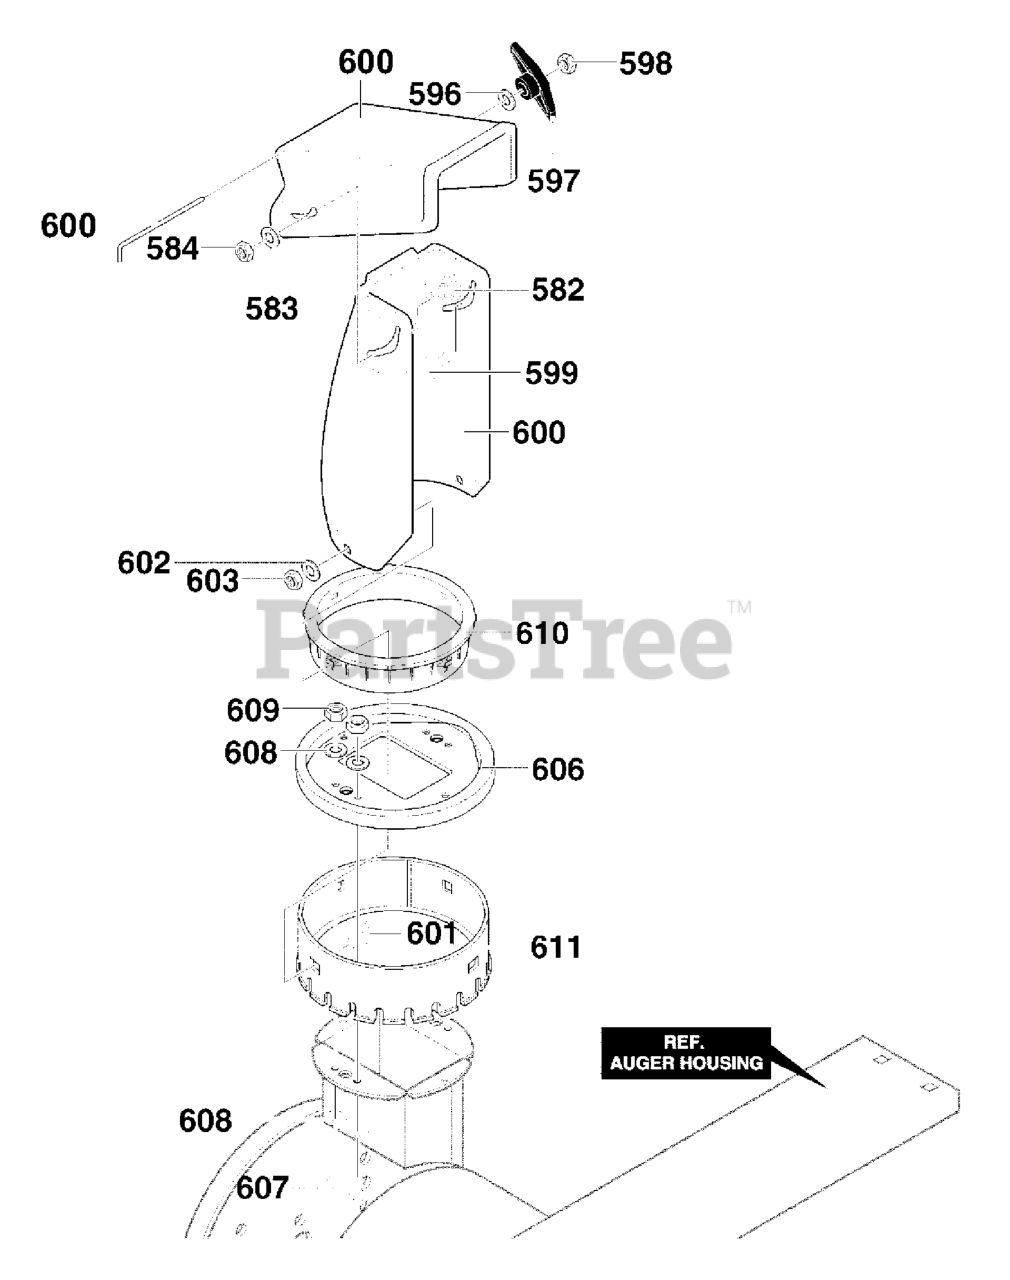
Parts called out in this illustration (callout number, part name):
582	SCREW, 5/16-18 x 0.75
583	WASHER, FLAT .349X.69X.066
584	NUT, 5/16-18 REGHEXCTRLK
596	WASHER, FLAT .349X.69X.066
597	KNOB, T
598	NUT, 5/16-18 REGHEX
599	BOLT 5/16-18X1.25 CARR.
600	CHUTE, ASSEMBLY
601	BOLT, 5/16-18X1.00
602	FLATWASHER .349X.69X.066
603	NUT, 5/16-18
606	COLLAR, CHUTE
607	SCREW, 1/4-20X .75
608	FLATWASHER .281X .63X.065
609	NUT, 1/4-20 HEX NYLOCK
610	RETAINER, RING INNER
611	RETAINER, RING OUTER
